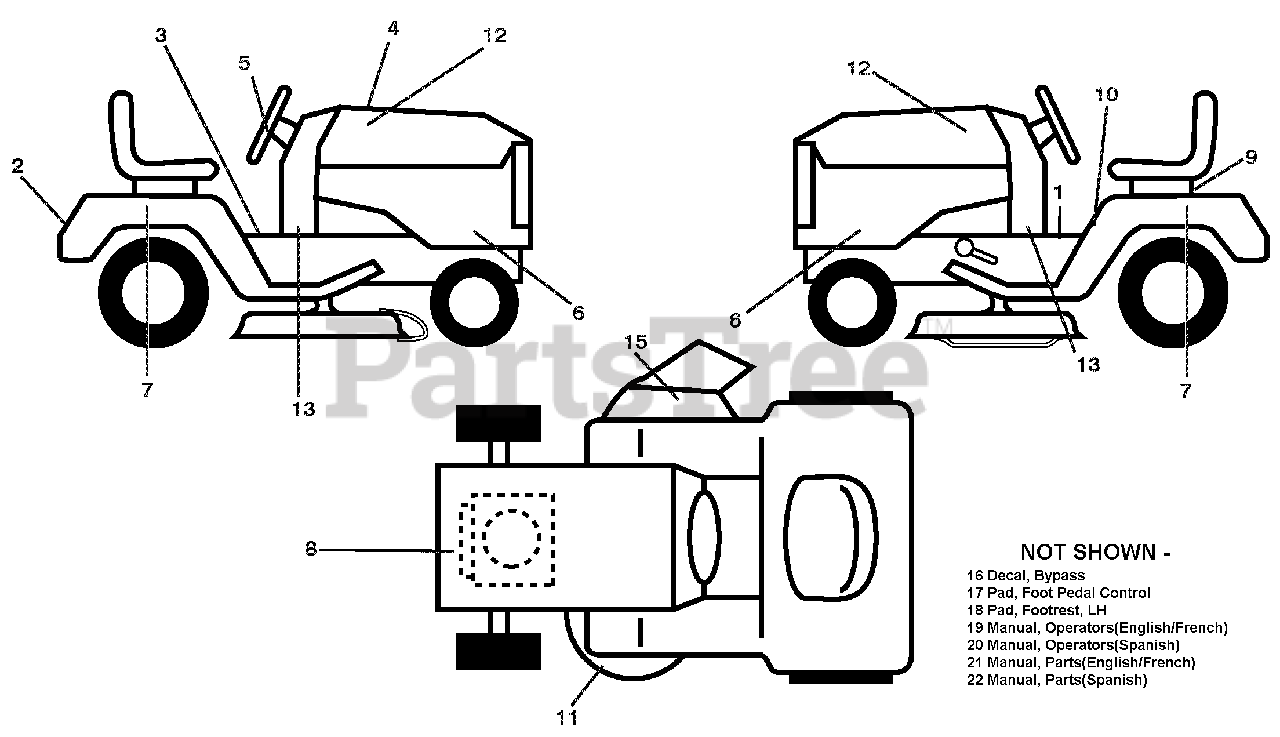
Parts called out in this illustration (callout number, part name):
1	DECAL.WARNING.START
2	DECAL.FENDER.REAR.ARIENS
3	DECAL.FENDER
4	DECAL.REPLACEMENT
5	DECAL.WHEEL.STEER.ARIENS
6	DECAL.SDPNL.PWRDBY B&S.ARIENS
7	DECAL.FENDER.SIDE.HYDRO
8	DECAL.ENGINE.HP
9	DECAL.BAT.DAN/POI P/L SYM.WPN
10	DECAL.FENDER
11	DECAL.V-BELT.SCH.
12	DECAL.HOOD.LH/RH.
13	DECAL, DASH.LOWER
15	DECAL DECK/DEFLECT. WARNING
